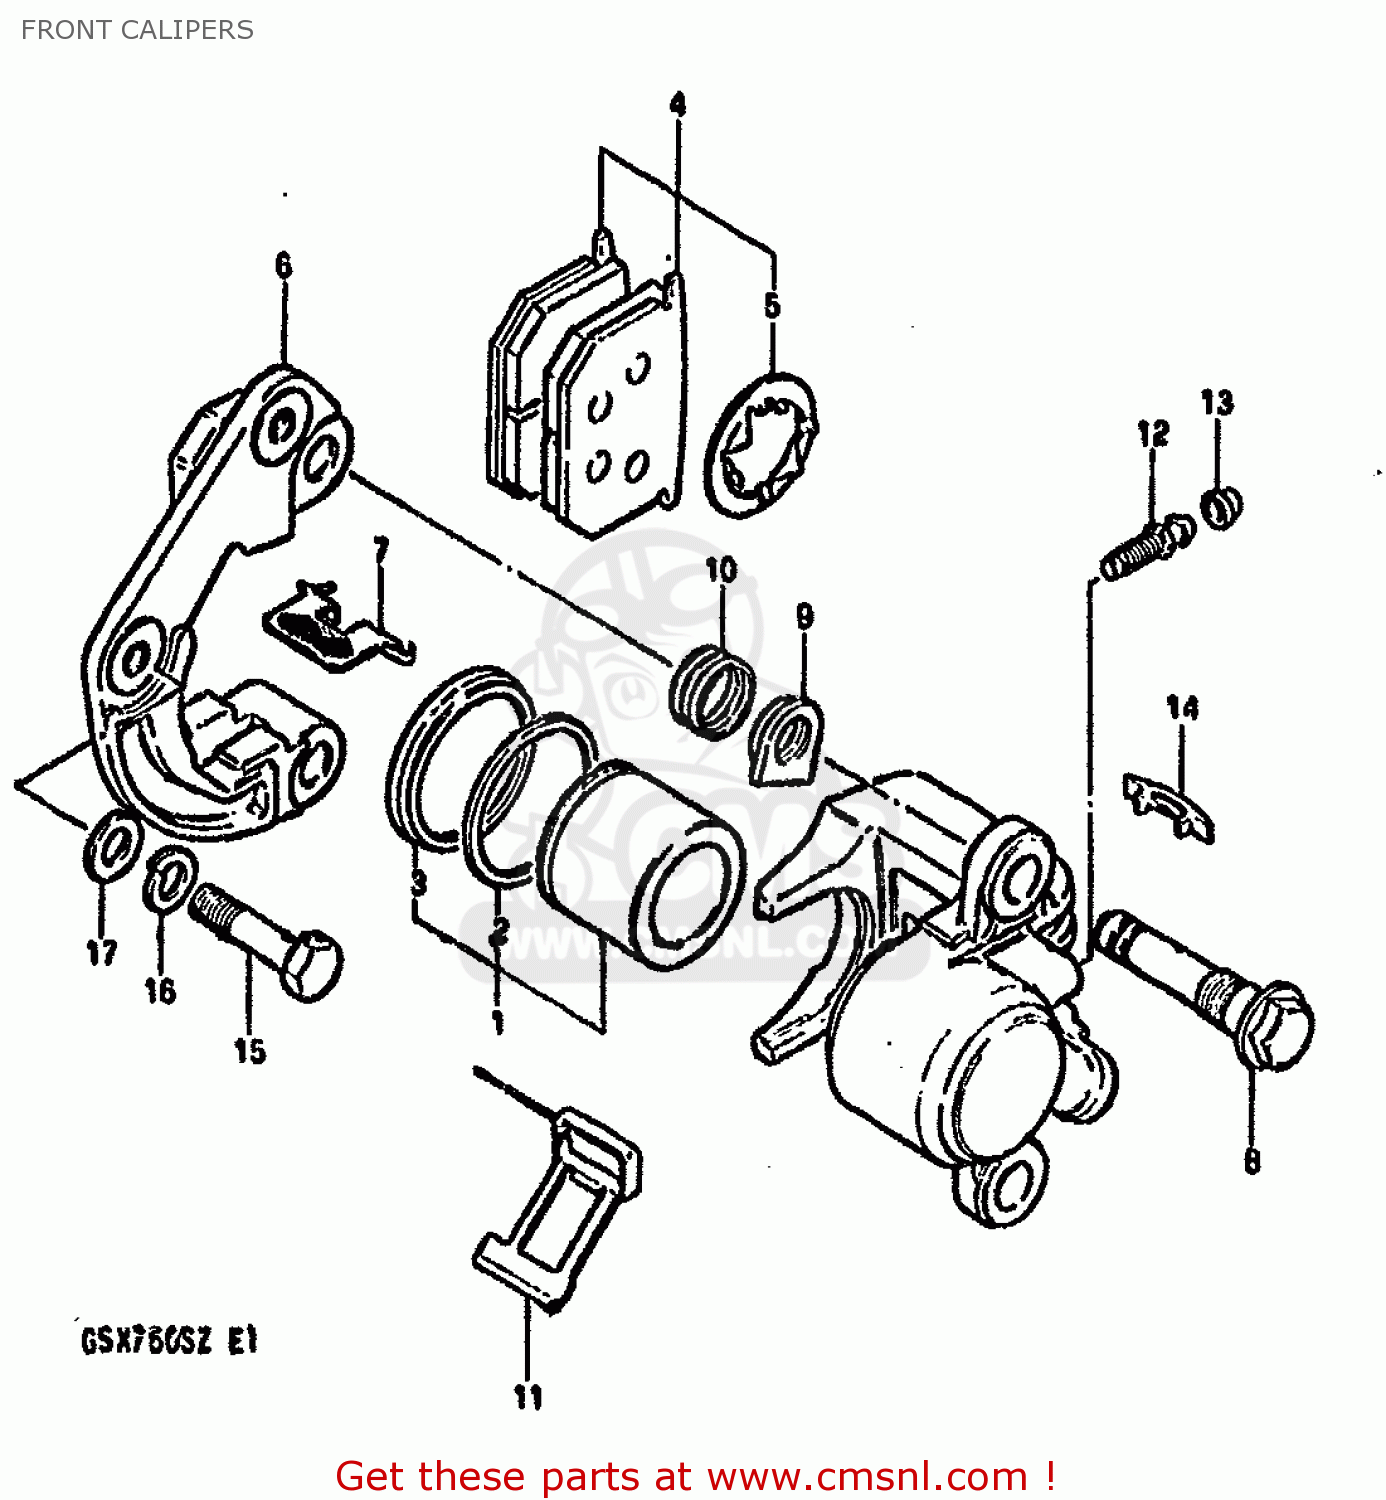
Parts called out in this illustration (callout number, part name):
1	PISTON SET
2	SEAL,PISTON
3	BOOT,PISTON
4	PAD & SHIM SET (MCA)
5	SHIM,PAD
6	HOLDER,CALIPER,LEFT
7	PAD,GUIDE
8	AXLE,CALIPER
9	NUT,CALIPER AXLE
10	BOOT
11	SPRING
12	BREATHER
13	CAP,BLEEDER PL
14	COVER,INDICATOR
15	BOLT
16	LOCK WASHER
17	WASHER
